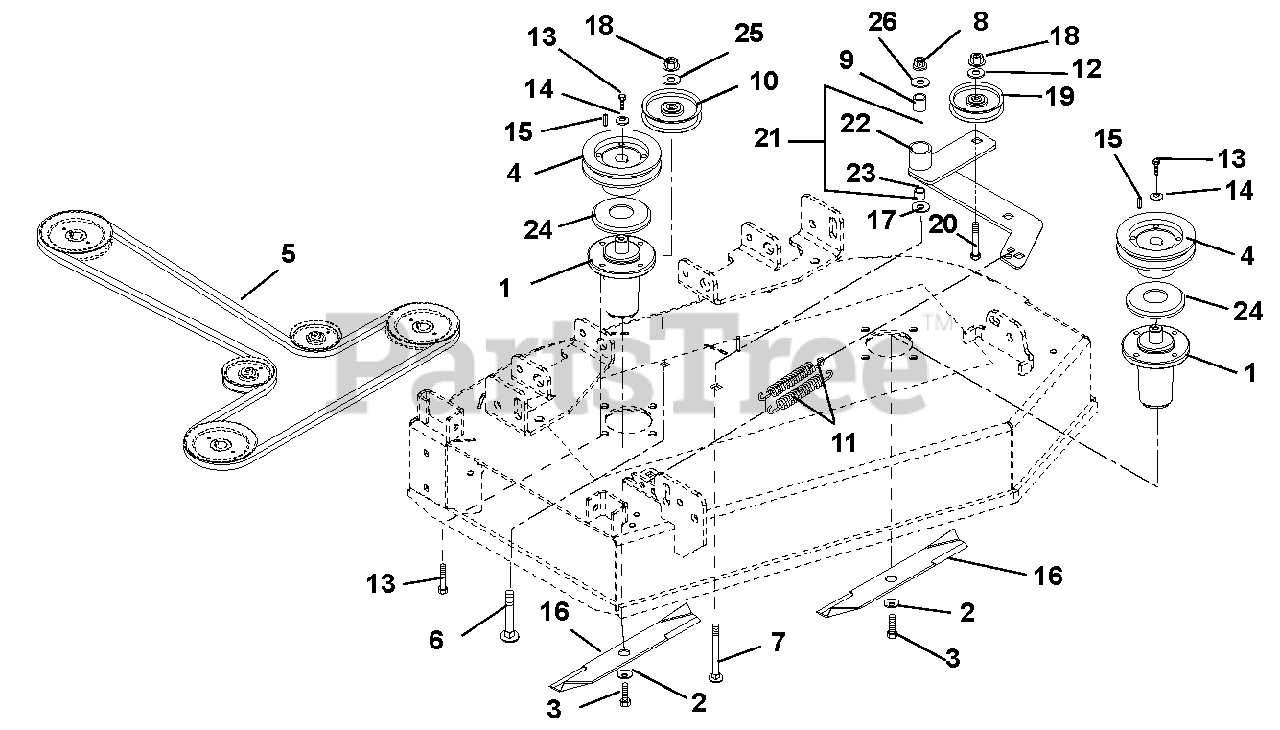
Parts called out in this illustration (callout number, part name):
1	Assembly, Maintenance Free Spindle
2	Washer, Bellville .63 x 1.625 x .14
3	Bolt, Hex .62-18 x 1.75 Grade 8
4	Sheave, 5.00 Spindle (1.00 I.D.)
5	V-Belt, B-Section 49.68 x .62548.80 x .625
6	Bolt, Round Head Square Neck .38-16 x 3.0
7	Bolt, Round Head Square Neck .50-13 x 3.50
8	Nut, Nyloc Flange .50-13
9	Bushing, Spacer .505/.500 x .999/.996 x 2.05/2.03
10	Idler, Flat 4.00 x .38 (2.00 W)
11	Spring, Extension
12	Washer, Flat Steel .375 x 1.125 x .065
13	Bolt, Hex .38-16 x 1.00 EP30
14	Washer, Flat Steel .406 x 1.50 x .245
15	Key, Square .25 x .25 x 1.00
16	Blade, Mulching 50" Mower
17	Washer, Flat Steel .531 x 1.250 x .100
18	Nut, Nyloc Flange 3/8-16
19	Idler, Flat 4.00 x .38 (1.00 W)
20	Bolt, Round Head Square Neck .38-16 x 2.00
21	Assembly, Idler Pivot Arm (Contains Items 22 & 23)
22	Weldment, Idler Pivot Arm
23	Bushing, 1.00 x 1.125 x 1.936
24	Slinger, Dust
25	Seal, Idler Bearing
26	Washer, Flat Steel 511 x 1.441 x .125
